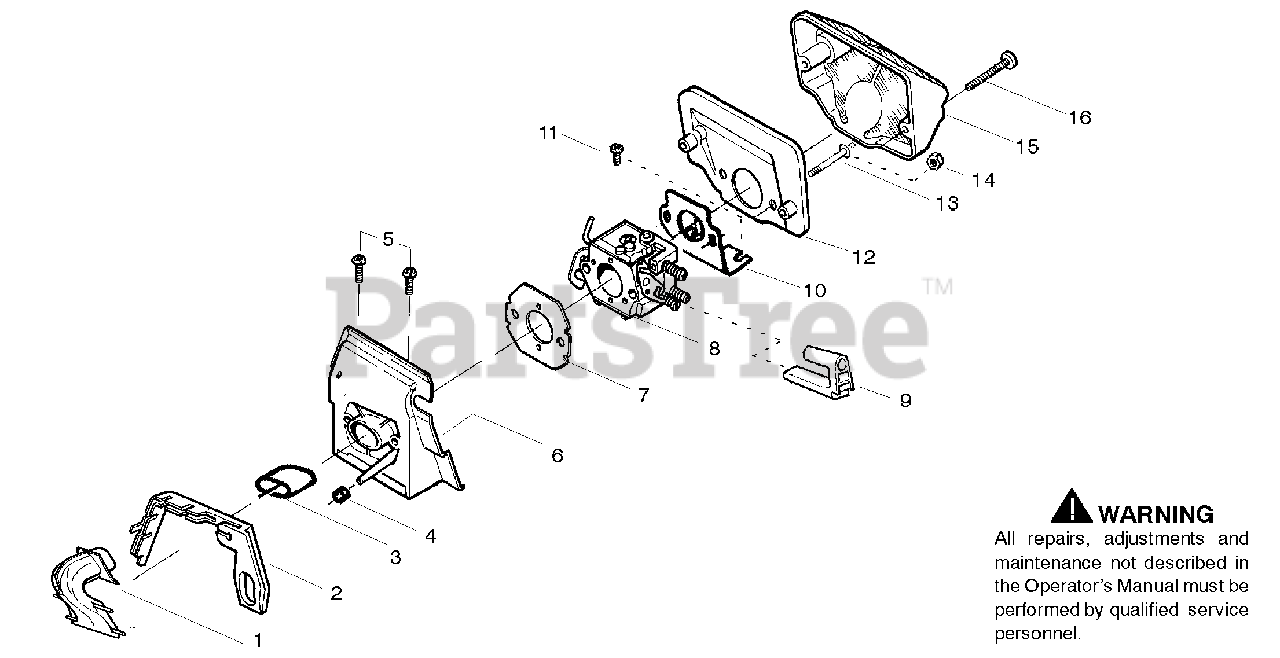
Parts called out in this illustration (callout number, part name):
1	Assy-Turbo Air Cleaner
2	Seal-Turbo Clean
3	Sleeve-Intake
4	Seal-Impulse
6	Adapter-Carb.
7	Gasket-Carburetor
8	Carburetor
9	Grommet-Final
10	Plate-Support
12	Air Filter-Bottom
13	Stud-Carb.
15	Air-Filter-Top
